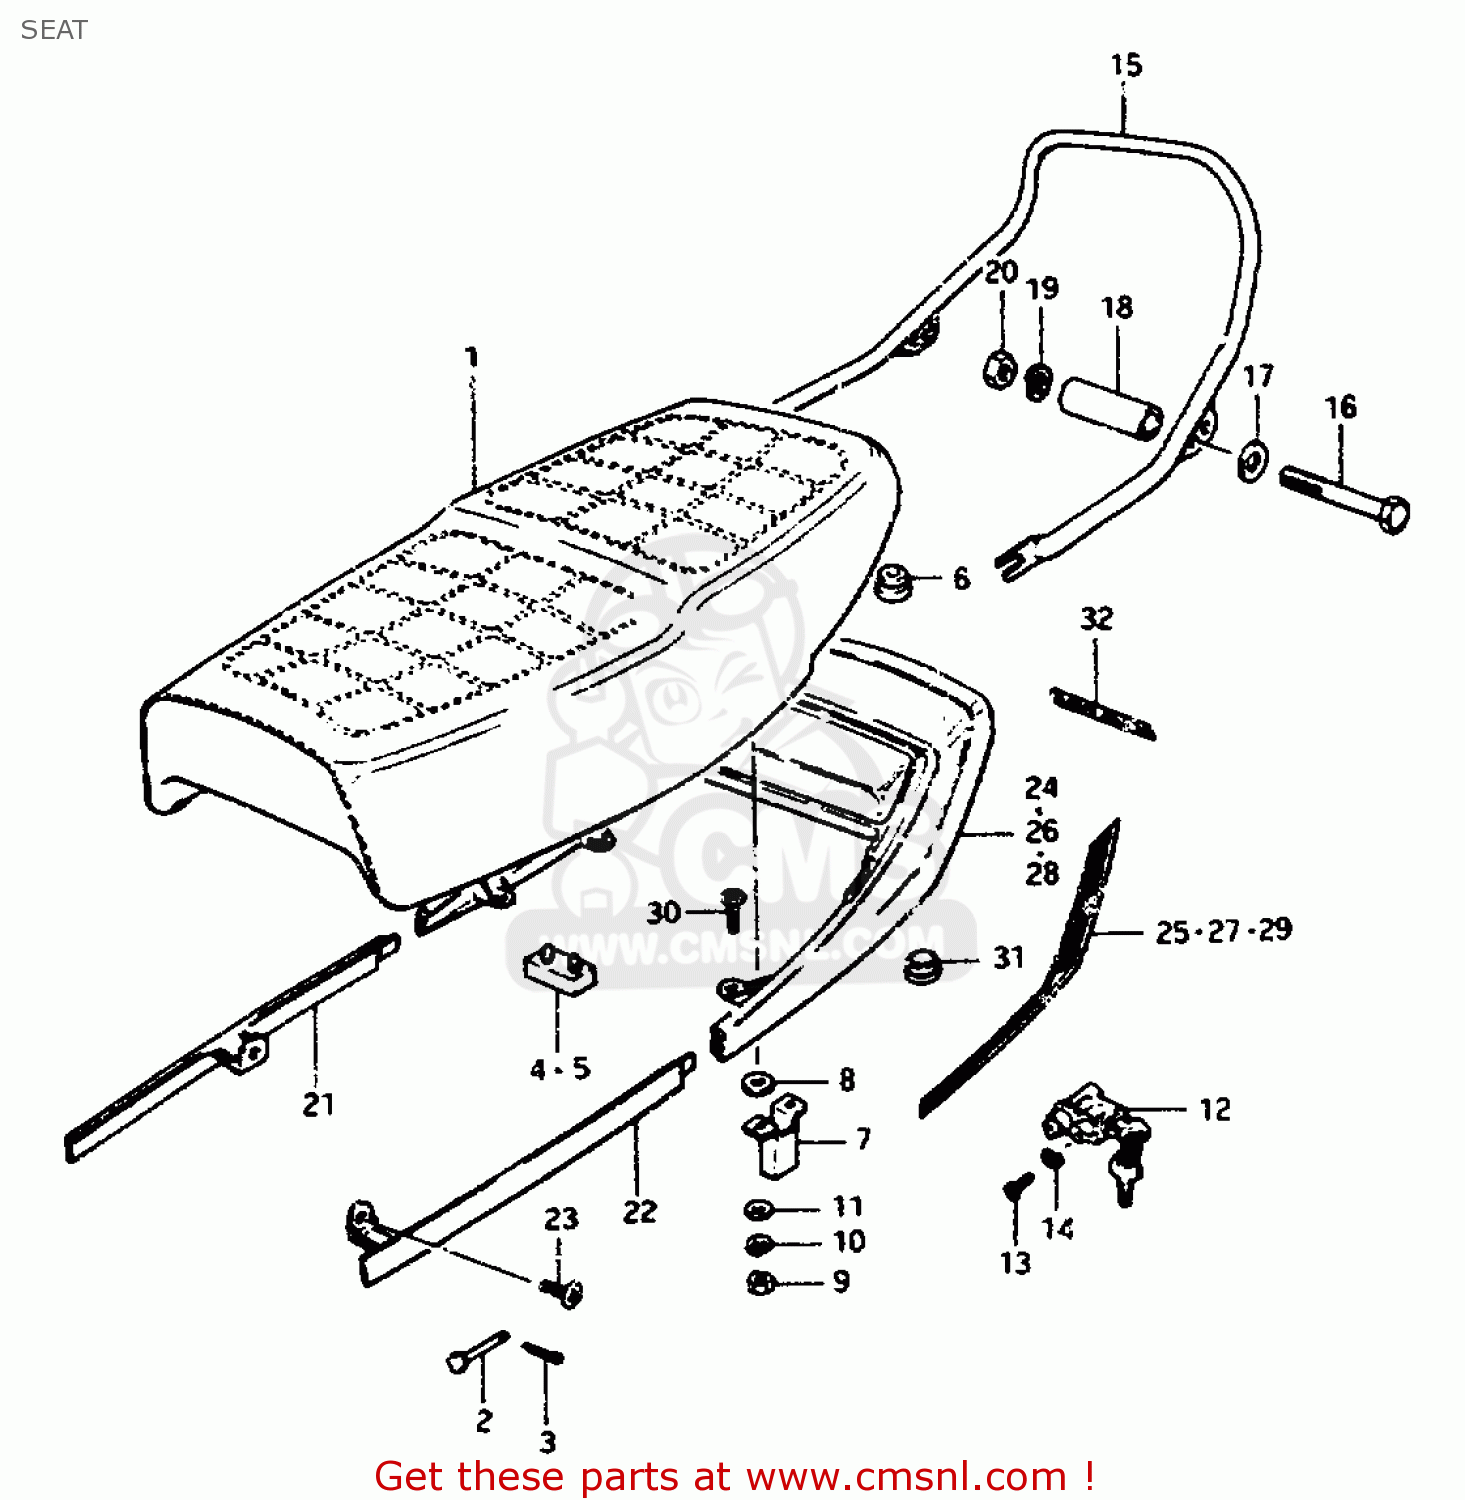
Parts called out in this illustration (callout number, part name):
1	SEAT ASSY
2	PIN
3	PIN
4	CUSHION
5	CUSHION
6	CUSHION(11.5X22X20)
7	PLATE,CLAMP GUIDE
8	WASHER(6.5X18X1)
9	NUT
10	LOCK WASHER
11	WASHER
12	LOCK ASSY,SEAT
13	SCREW
14	LOCK WASHER
15	BAR, PILLION RIDER
16	BOLT 10X65
17	WASHER
18	SPACER
19	LOCK WASHER
20	NUT
21	PLATE, SEAT LOWER RH
22	PLATE, SEAT LOWER LH
23	SCREW
24	TAIL COVER, SEAT
25	TAPE SET
26	TAIL COVER, SEAT
27	TAPE SET
28	TAIL COVER, SEAT
29	TAPE SET
30	SCREW
31	PLUG(OD:19)
32	EMBLEM,SEAT TAIL COVER RR
